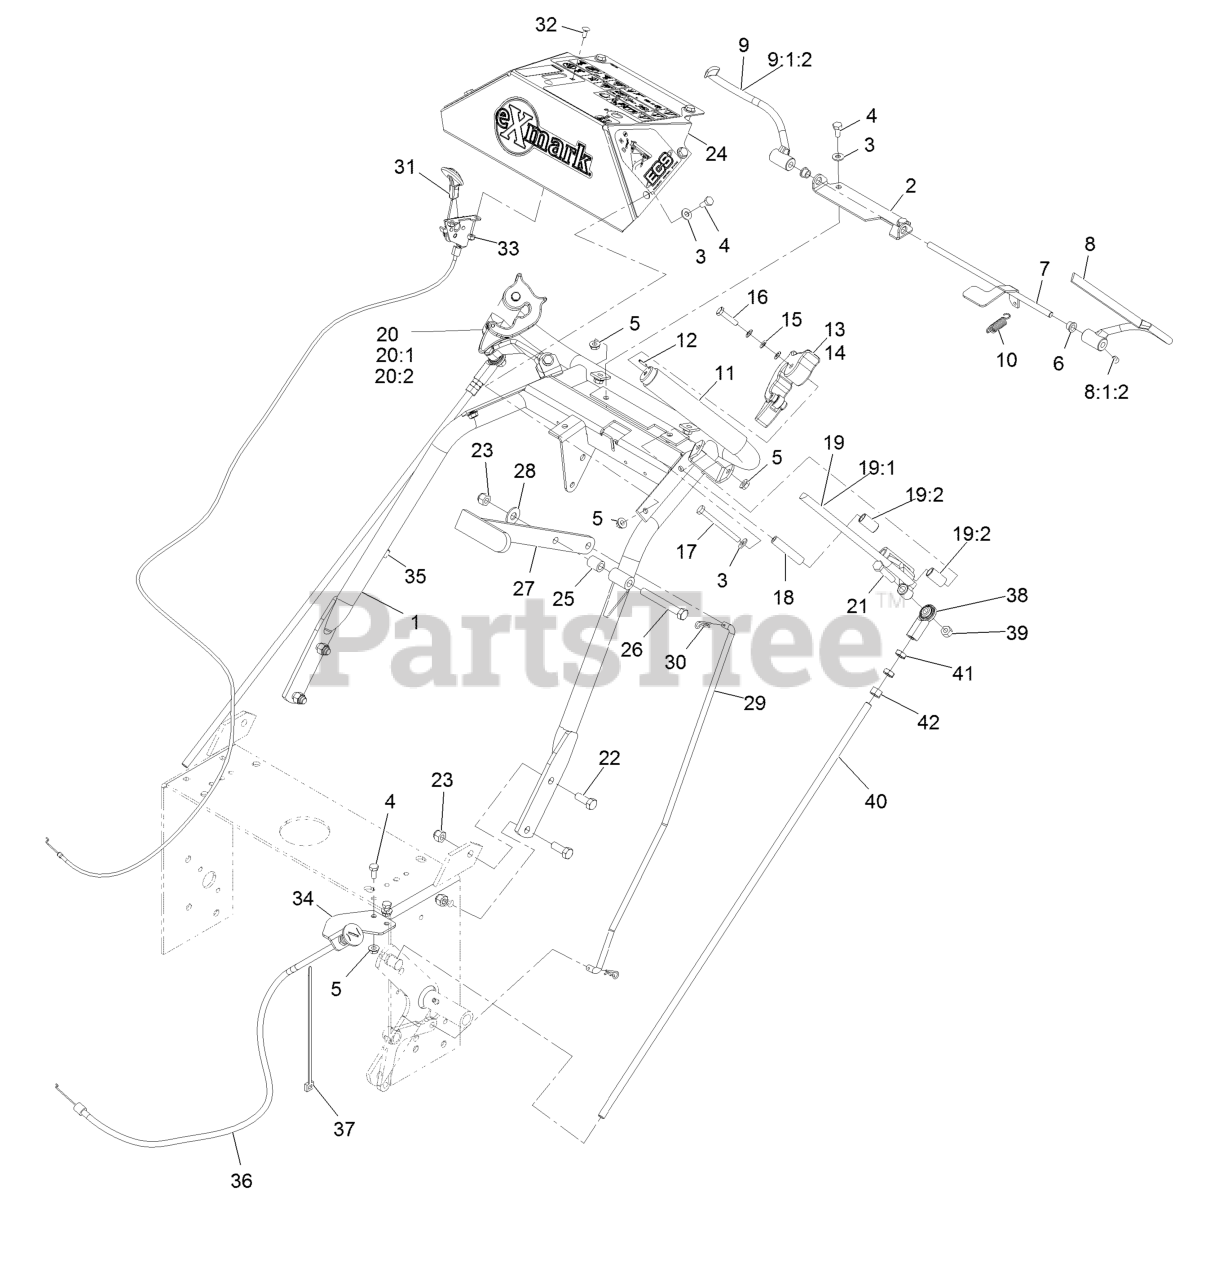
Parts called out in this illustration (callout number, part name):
1	Handle Weldment
2	Bracket, Opc Axle
3	Washer-1/4 SAE
4	Screw-HH 1/4-20 X 5/8
5	Nut-Whizlock 1/4-20
6	Bushing-Nylon
7	Rod Weldment, OPC
8	Wld,LH OPC Lever
8:1:2	Setscrew-5/16-24 X 5/16
9	Wld,RH OPC Lever
9:1:2	Setscrew-5/16-24 X 5/16
10	Spring-Extension
11	Grip-Bar, Handle
12	Pin-Spring
13	Latch, Thumb LH
14	Latch, Thumb RH
15	Washer-Spring Disc 1/4
16	Screw-HH 1/4-20 X 1 1/8 W/Nylon
17	Screw-HH 1/4-20 X 2 3/4
18	Bushing-Lever, Drive
19	Asm, Drive Lever LH
19:1	Wld,LH Drive Lever
19:2	Bushing, Sleeve
20	Asm, Drive Lever RH
20:1	Wld,RH Drive Lever
20:2	Bushing, Sleeve
21	Screw-HH 5/16-18 X 1 3/4
22	Screw-HH 3/8-16 X 1
23	Nut-Nyloc 3/8-16
24	Asm, Console (109-4649-03) W/Decals
26	Screw-HH 3/8-16 X 3
27	Clutch Lever W/Grip
28	Washer-3/8 Std
29	Linkage, Upper
30	Hairpin-Cotter
31	Control, Throttle
32	Bolt-Carriage #10-24 X 1/2
33	Nut-Nyloc #10-24
34	Bracket-Cable, Choke
35	Clip-Cable
36	Cable-Choke
37	Tie-Cable 7 15/16 (Large)
38	Balljoint
39	Nut-Nyloc 5/16-18
40	Linkage, Wheel Drive
41	Nut-Jam 3/8-24
42	Nut-Hex 3/8-24
